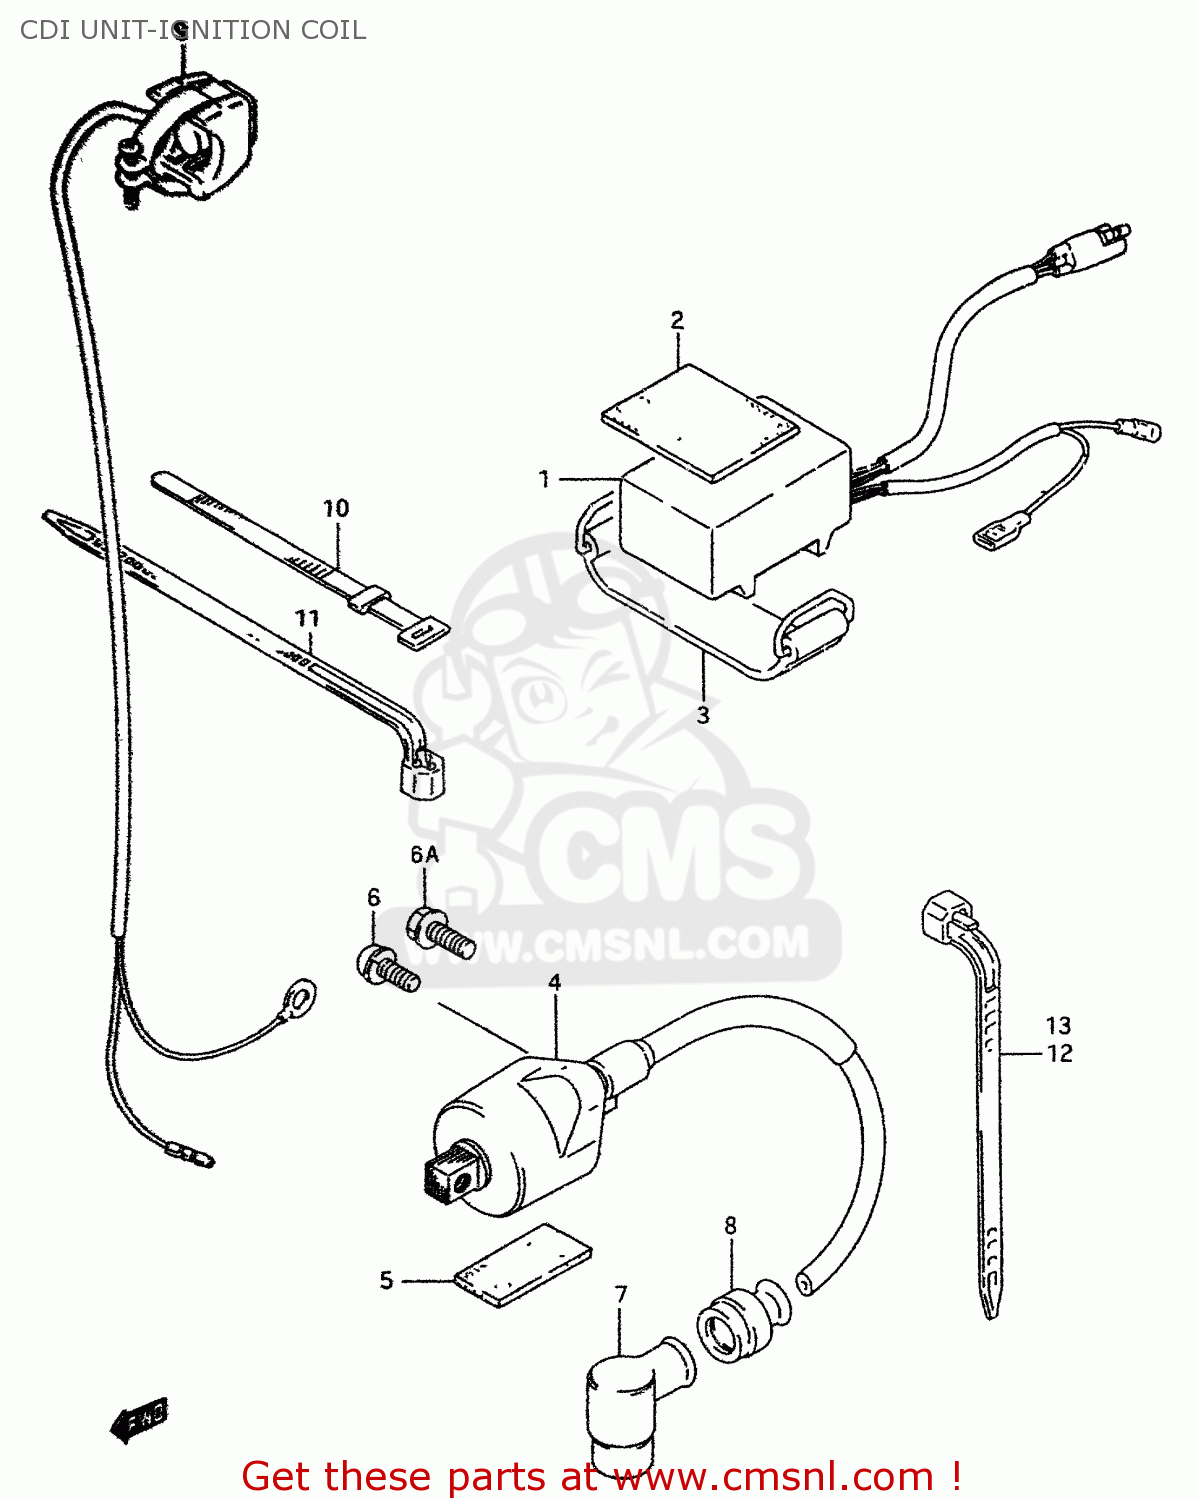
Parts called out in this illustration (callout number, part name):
1	CDI UNIT
2	PROTECTOR(170X95X3.0)
3	BAND
4	COIL ASSY,IGNITION
5	PROTECTOR(170X95X3.0)
6	SCREW(6X21)
6A	SCREW
7	CAP,SPARK PLUG
8	SEAL,HIGH TENSION CORD
9	SWITCH ASSY,ENGINE STOP
10	CLAMP(L:120)
11	CLAMP L:165
12	CLAMP(L:125)
13	CLAMP(L:95)
